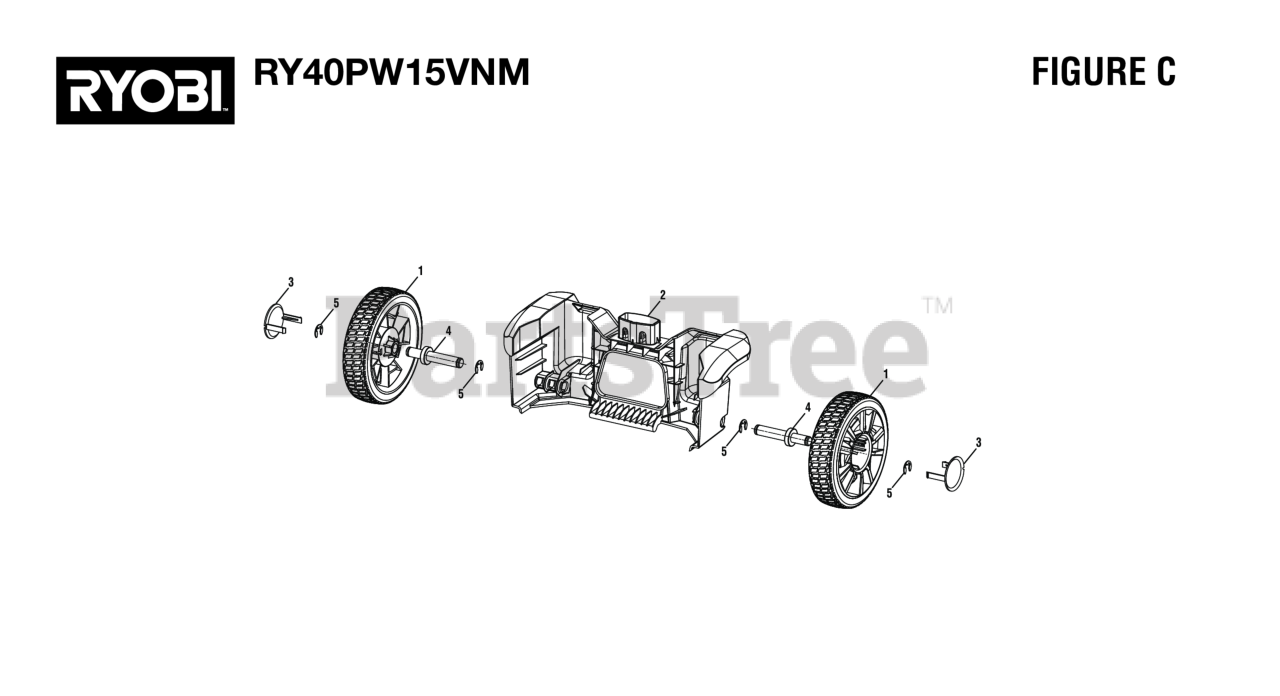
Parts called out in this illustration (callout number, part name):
2	Wheel Base Bracket
3	Wheel Cover
4	Wheel Axle
5	Retaining Ring
